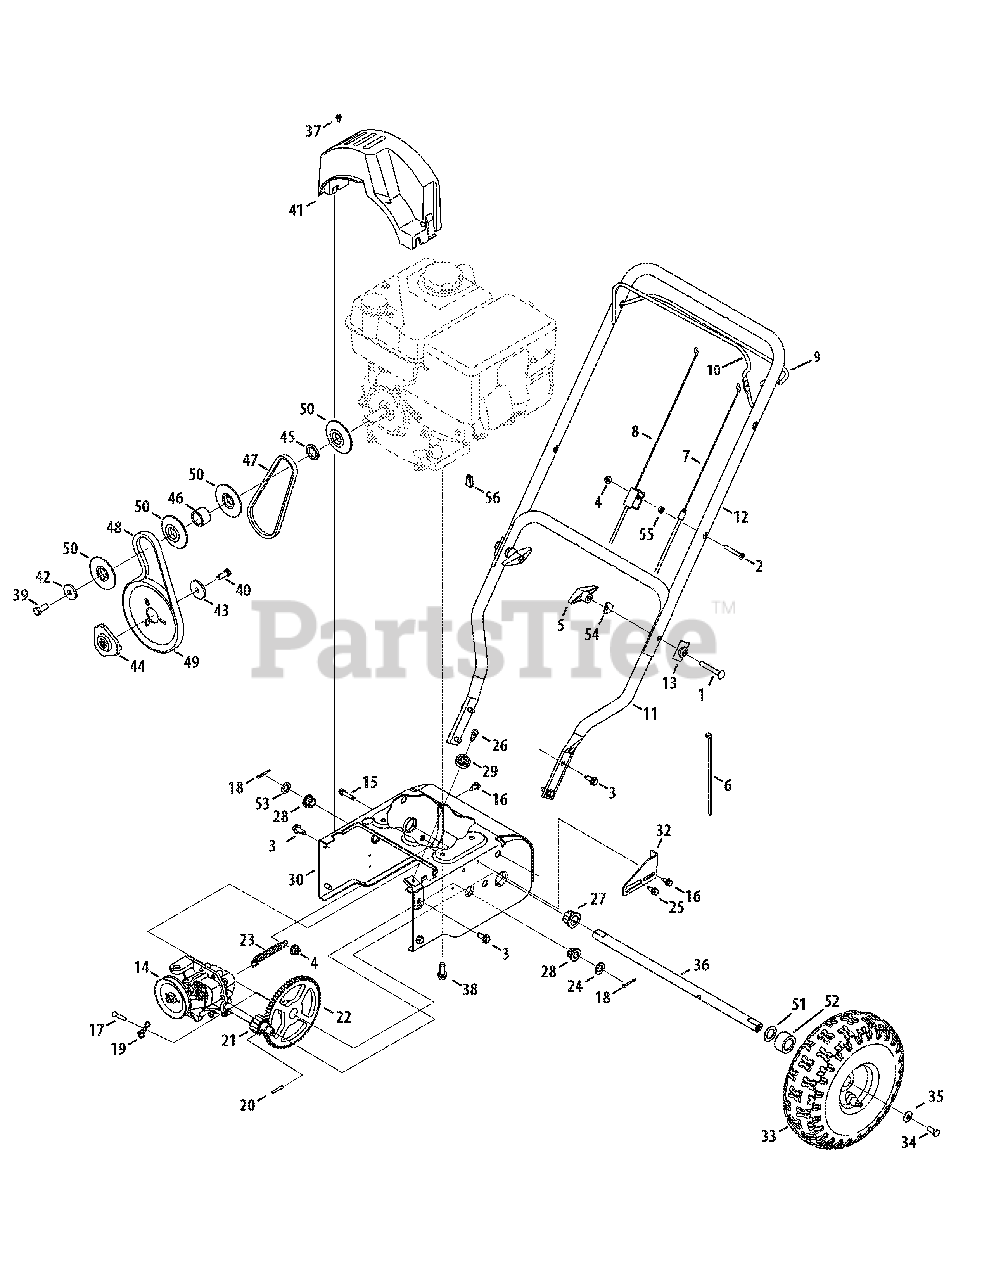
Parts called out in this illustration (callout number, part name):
1	Carriage Screw 5/16-18 x 2.25
2	Mach. Screw 1/4-20 x 1.825
3	Screw 5/16-18 x .75
4	Flange Lock Nut 1/4-20
5	Wing Knob 5/16-18
6	Cable Tie
7	Drive Cable
8	Auger Cable
8	Fitting, Dual Cable
9	Auger Control
10	Drive Control
12	Upper Handle
13	Handle Tab
14	Transmission Assembly
15	TT Screw 1/4-20 x 1.25
16	Screw 1/4-20 x .625
17	Clevis Pin
18	Cotter Pin 1/8 x 1.0
19	Bow Tie Cotter Pin 72
20	Roll Pin
21	Pinion 14T
22	Gear 70T
23	Extension Spring
24	Flat Washer
25	Shoulder Screw 1/4-20
26	Shoulder Screw 1/4-28
27	Hex Flange Bearing
28	Hex Flange Bearing
29	Cable Roller
30	Drive Housing Frame
31	Auger Cable Bracket
33	Wheel Assy. Snow Hog Gray
34	Lock Bolt 5/16-24 x .75
35	Bell Washer .34 x .872 x .06
37	Hex Screw #10-16 x .500
38	TT Sems. Screw 3/8-16 x 1.0
39	Hex Bolt 3/8-24 x .875
40	Lock Bolt 5/16-24 x .875
41	Belt Cover
42	Flat Washer .406 ID x 1.25 OD
43	Flat Washer .34 ID x 1.50 OD
44	Pulley: Adapter .75 Dia.
45	Spacer .876 x 1.25 x .19
46	Spacer .876 x 1.25 x .86
47	V-belt 3/8 x 21.108 Lg.
48	V-belt 3/8 x 26.375 Lg.
49	Auger Pulley
50	Pulley Half
51	Flat Washer .793 x 1.24 x .06
53	Flat Washer .53 x .93 x .05
54	Saddle Washer
55	Spacer
56	Engine Accessory Cap
